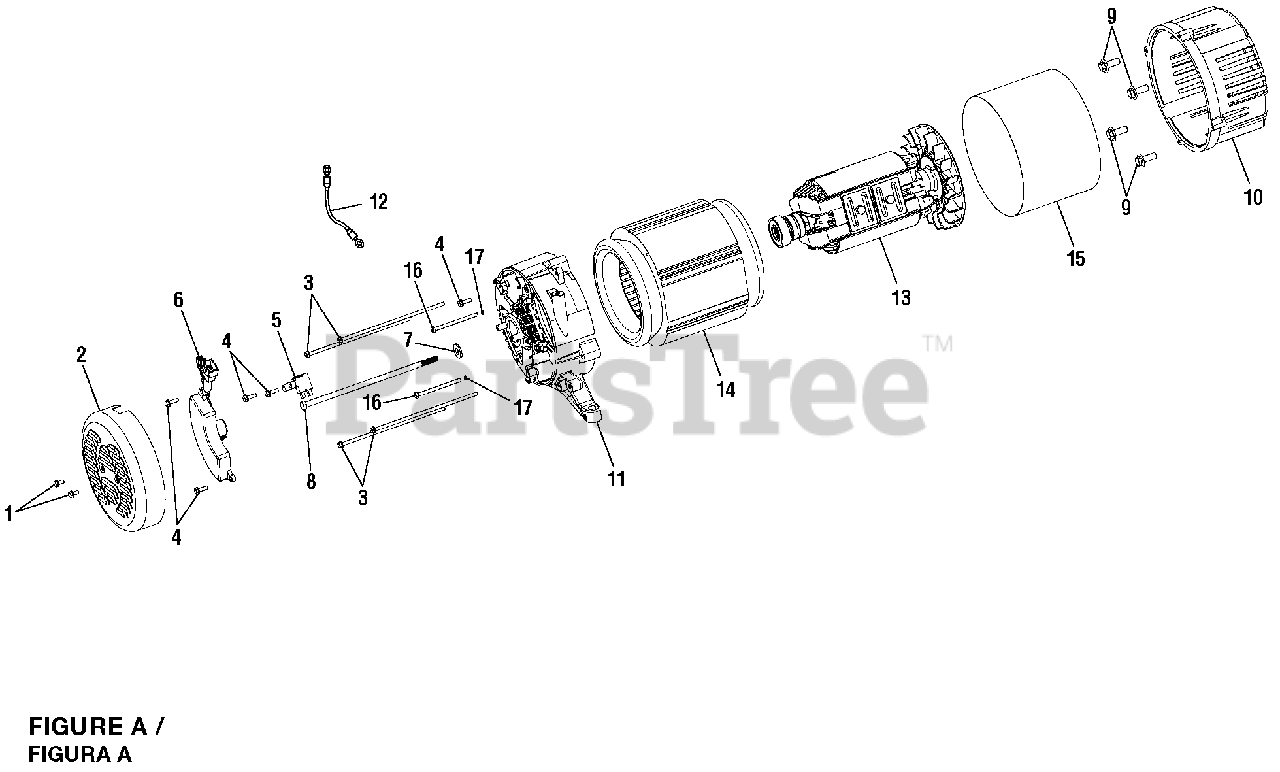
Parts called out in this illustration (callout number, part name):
1	Bolt (M5 x 10 mm, Flange Hex Hd.)
2	Brush Cover
3	Bolt (M6 x 164 mm)
4	Bolt (M5 x 16 mm, Flange Hex Hd.)
5	Brush Assembly
6	Automatic Voltage Regulator
7	Washer ( 5/16 in.)
8	Bolt (5/16-24 x 215 mm, Hex. Hd.)
9	Bolt (3/8-18 x 1-1/4 in.)
10	Engine Adapter
11	Bearing Support
12	Bonding Wire
13	Rotor Assembly
14	Stator Assembly
15	Generator Head Cover
16	Bolt (M5 x 75 mm)
17	Lock Washer (M5)
